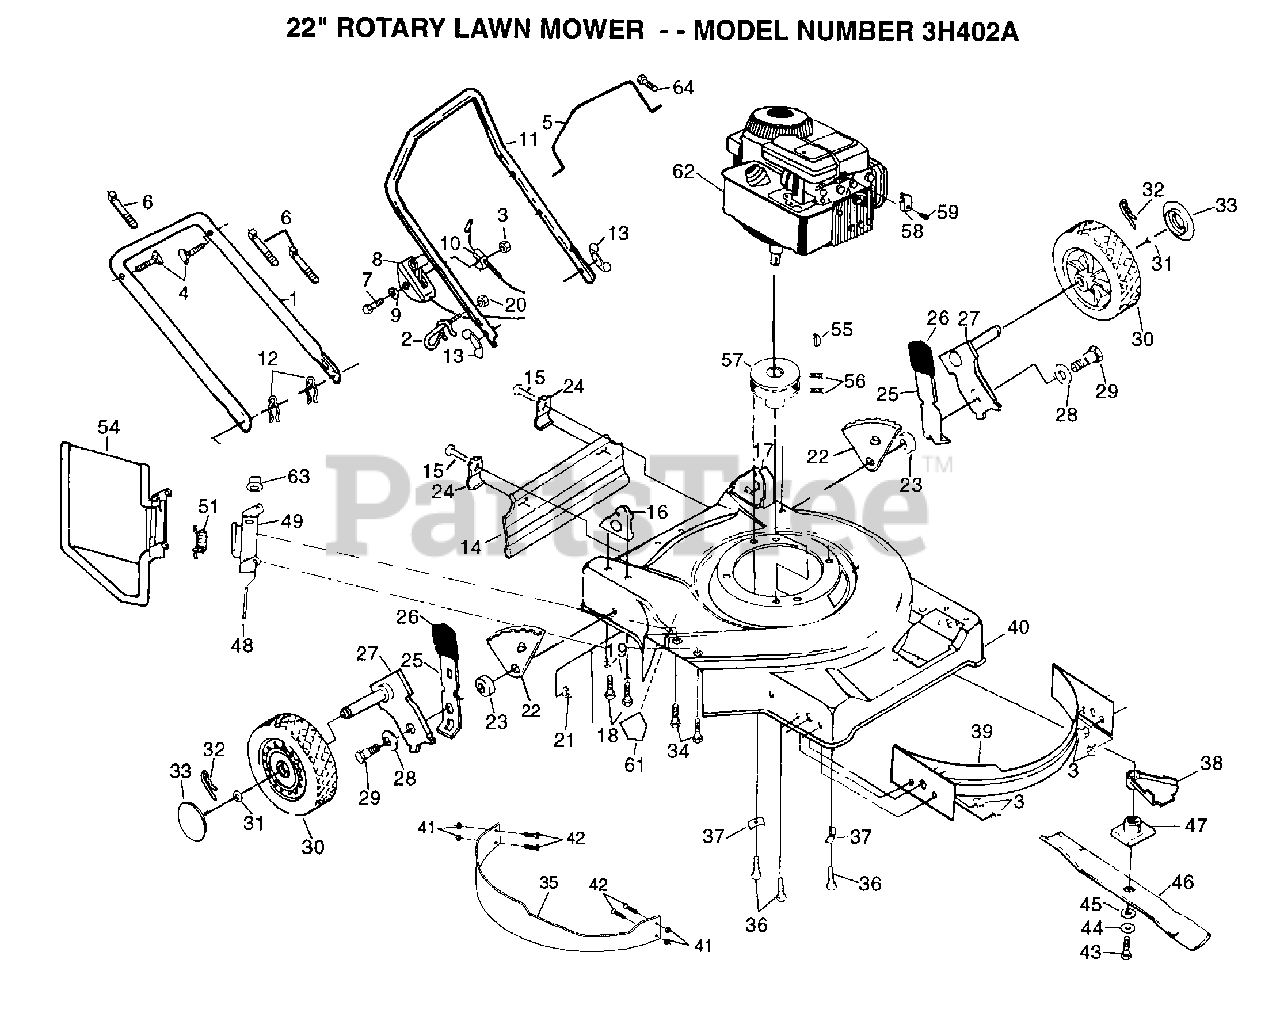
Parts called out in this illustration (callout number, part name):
2	ROPE GUIDE
4	BOLT.HANDLE.LM
5	CONTROL BAR
8	"CONTROL, THROTTLE"
9	WASHER PM
10	"CABLE,ENG ZONE CO"
12	HAIRPIN COTTER
13	"NUT,WING PM"
15	TAPPING SCREW
18	SCREW
19	STEEL WASHER
20	NUT
21	LOCKNUT PM
24	"BRKT,DEFL PM"
25	SPRING SELECTOR
26	KNOB PM
27	AXLE ARM
28	"WASHER, BELLEVIL."
31	WASHER
32	RETAINER CLIP PM
33	HUB CAP
34	SCREW
35	BAFFLE.MULCH.22SD
36	SCREW
38	DEBRIS SHIELD
39	BAFFLE FRONT 22SD
41	LOCKNUT
43	SCREW
44	LOCKWASHER
45	"WASHER,HARDEN"
47	ADAPTOR.BLADE.LM
48	"ROD,HINGE "
49	"BRKT,HSG"
51	"SPRING,TORSION"
55	HI PRO KEY PM
56	SCREW
57	ENGINE.PULLEY.FWG
58	CABLE CLAMP
59	SCREW PM
61	DECAL-DANGER PM
63	PUSH ON SPEED NUT
64	"SCREW,PAN HD"
